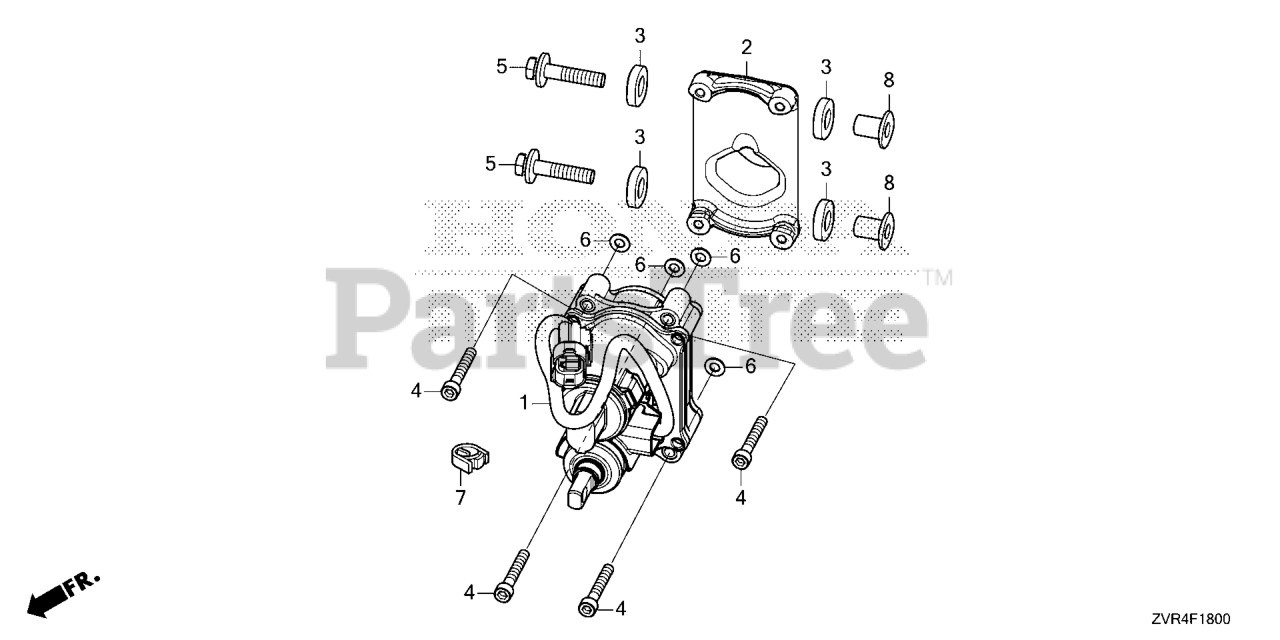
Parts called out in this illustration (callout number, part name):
1	ACTUATOR, SHIFT
2	BRKT, SHIFT ACTUATOR
3	RUBBER, CUSHION
4	BOLT, SOCKET (6X38)
5	BOLT-WASHER (8X40)
6	WASHER (6MM)
7	CLIP, WIRE HARNESS
8	COLLAR (8X17)
